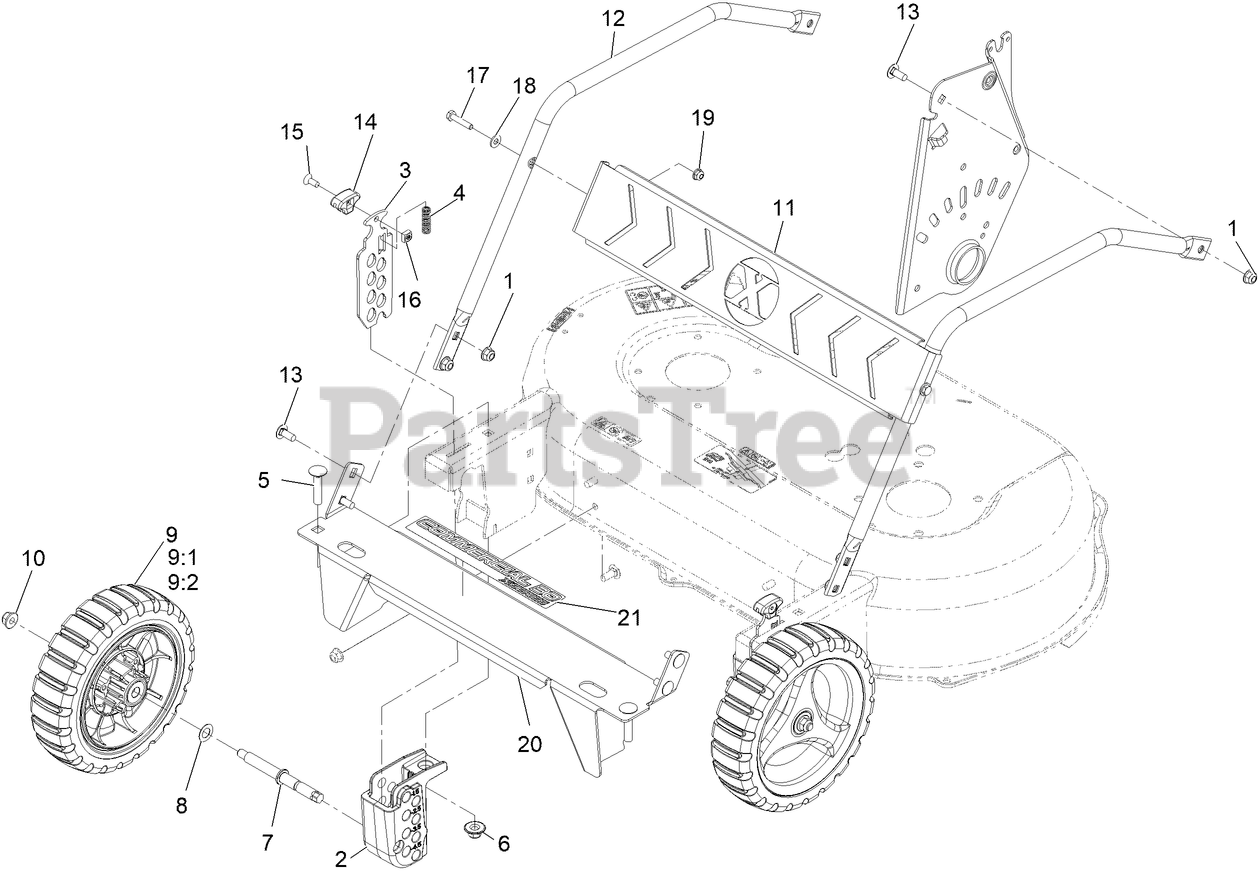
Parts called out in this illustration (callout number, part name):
1	NUT-HF, NI
2	BLOCK-FRONT QUADRANT
3	PLATE-ADJUSTER
4	SPRING-COMPRESSION
5	SCREW-CARR
6	Nut-Nyloc 3/8-16 Flg
7	AXLE-WHEEL
8	WASHER-PLAIN
9	WHEEL ASM, 9" W/BEARINGS
9:1	WHEEL ASM, 9
9:2	BEARING-BALL
10	NUT-HF, NI
13	SCREW-CARR
14	GRIP-HOC HANDLE
15	SCREW-HSFH
16	Square Nut 1/4-20,ATV CB
17	SCREW-HH
18	WASHER-FLAT
20	Bracket-HOC Front
21	DECAL-COMM 30 X-SERIES
